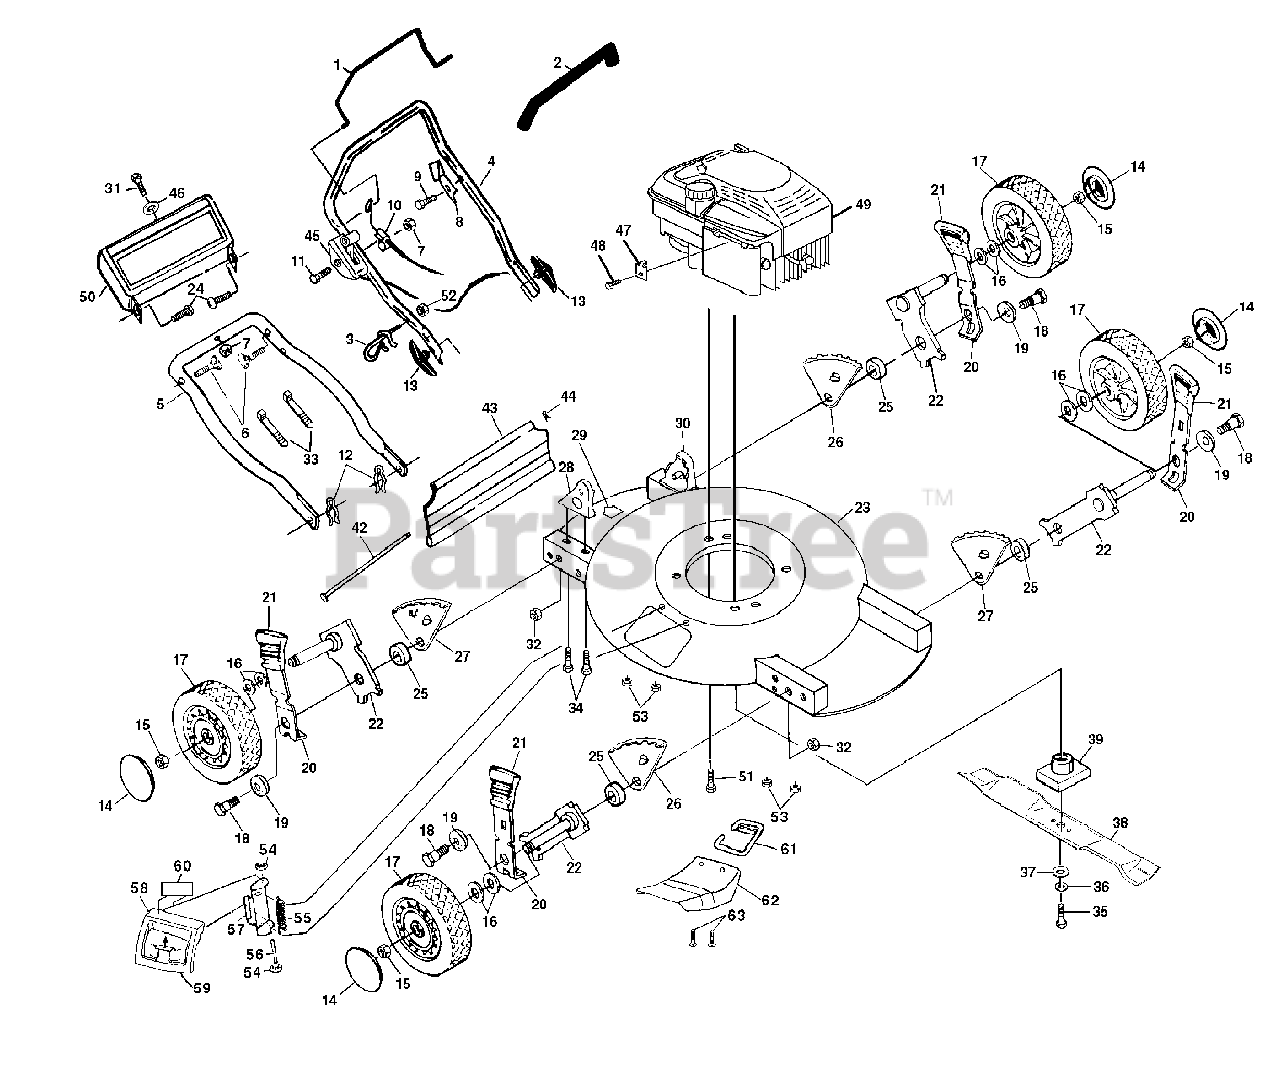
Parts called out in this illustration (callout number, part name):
1	Control Bar
2	Handle Grip
3	Rope Guide
4	Upper Handle
5	Lower Handle
6	Handle Bolt 5/16-18 x 1-3/4
7	Locknut 1/4-20
8	Up-Stop Bracket
9	Hex Washer Head Screw #10-24 x 1/2
10	Engine Zone Control Cable
11	Hex Washer Head Screw 1/4-20 x 2.12
12	Hairpin Cotter
13	Handle Knob
15	Hex Locknut 3/8-16
16	Washer
17	Wheel & Tire Assembly
18	Shoulder Bolt
19	Belleville Washer
20	Selector Spring
21	Selector Knob
22	Axle Arm Assembly
23	Lawn Mower Housing
25	Spacer
26	Wheel Adjusting Bracket (R.F./L.R.)
27	Wheel Adjusting Bracket (L.F./R.R.)
28	Handle Bracket Assembly (Right)
29	Danger Decal
30	Handle Bracket Assembly (Left)
31	Screw
32	Locknut 3/8-16
33	Wire Tie
34	Thread Cutting Screw 5/16-18 x 3/4
35	Hex Head Screw 3/8-24 x 1-3/8
36	Helical Lockwasher 3/8
37	Hardened Washer
39	Blade Adapter
42	Deflector Rod
43	Rear Deflector
44	Retainer Clip
45	Throttle Control
47	Cable Clamp
48	Thread Rolling Screw #10-32 x 5/8
50	Trim Plate
51	Hex Head Screw, Self Tap. 3/8 - 16 x 1.1
52	Keps Locknut 1/4-20
53	Locknut
54	External E-Ring
55	Torsion Spring
57	Housing Assembly Bracket
58	Mulcher Door
59	Door Latch
61	Chute Mounting Bracket
62	Mulcher Deflector
63	Truss Head Screw
